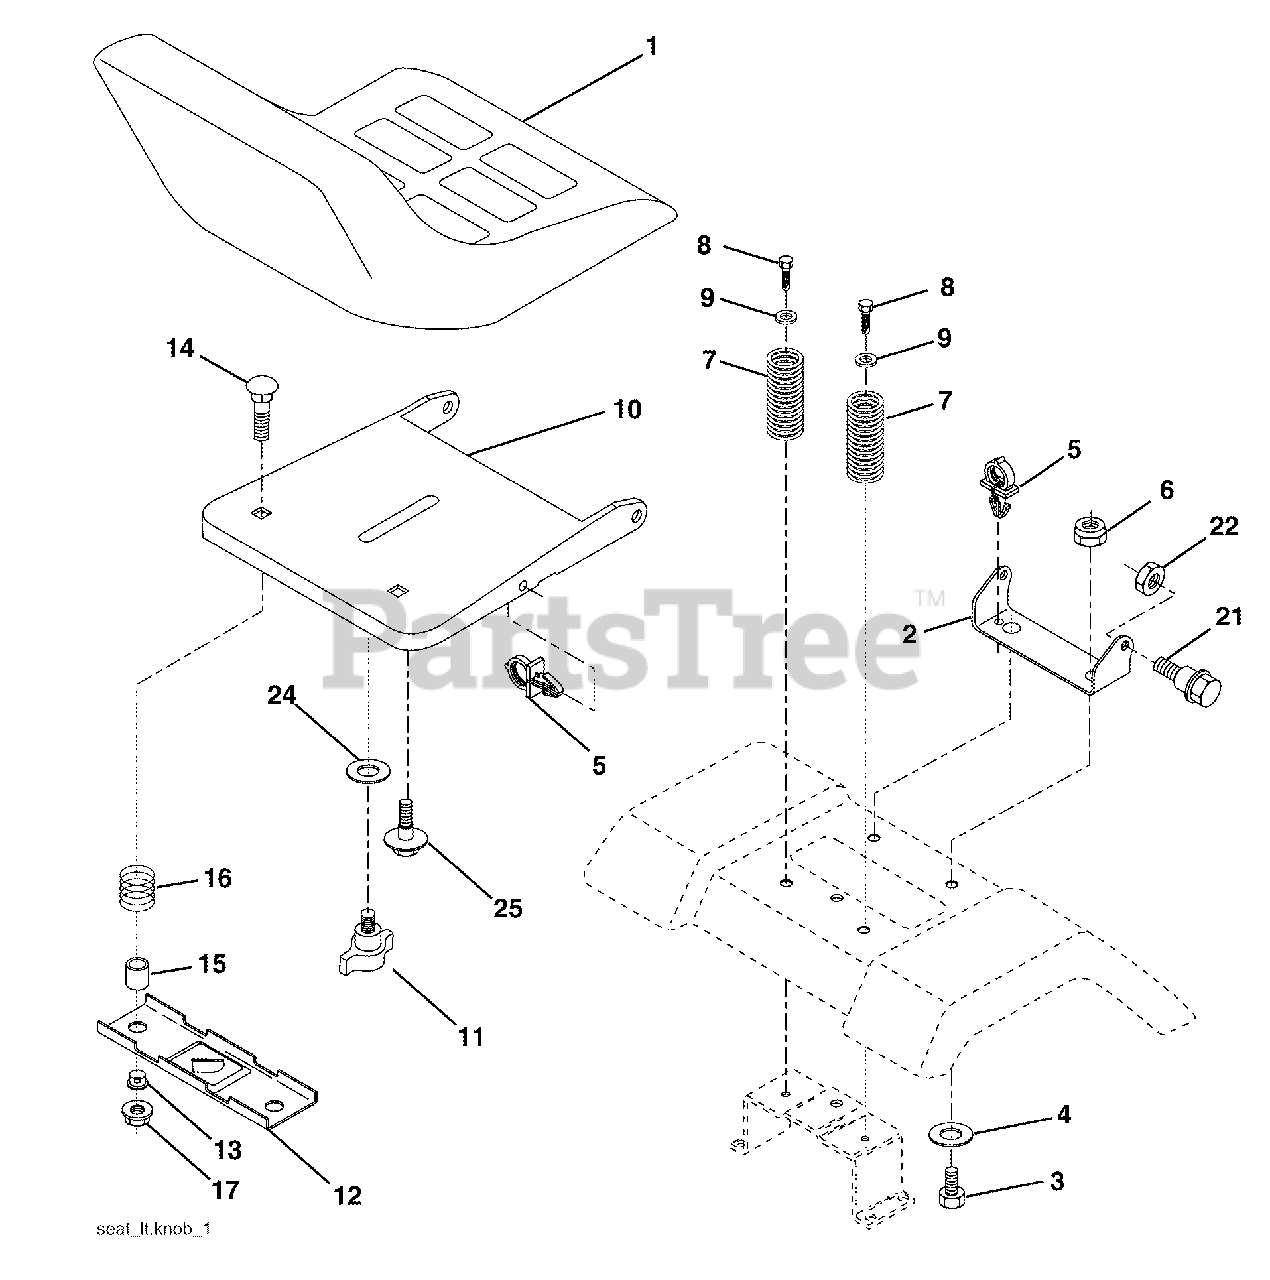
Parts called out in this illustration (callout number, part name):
1	Seat
2	Bracket Pivot Seat 8 720
3	Bolt Fin Hex 3/8-16 unc x 1
4	Washer 13/32 x 1 x 10 Ga.
5	Clip Push-In
6	Nut Hex w/Ins. 3/8-16 unc
7	Spring Seat Cprsn 2 250 Blk Zi
8	Screw 3/8-16 x 1-1/2 Smgml Tap/R Z
9	Washer 13/32 x 1 x 14 Ga.
10	Pan Seat
11	Knob Seat Adj. Wingnut
12	Bracket Mounting Switch
13	Bushing Snap Blk Nyl 50 Id
14	Bolt Rdhd Sqnk 1/4-2 x 1-1/2
16	Spring Cprsn
17	Nut Lock 1/4 Lge Flg Gr. 5 Zinc
21	Bolt Shoulder 5/16-18 unc-2a Blk DA
22	Nut Hex Lock W/Ins 5/16-18
24	Washer 17/32 x 13/16 x 12 Ga.
25	Bolt Shoulder 5/16-18 x 62
